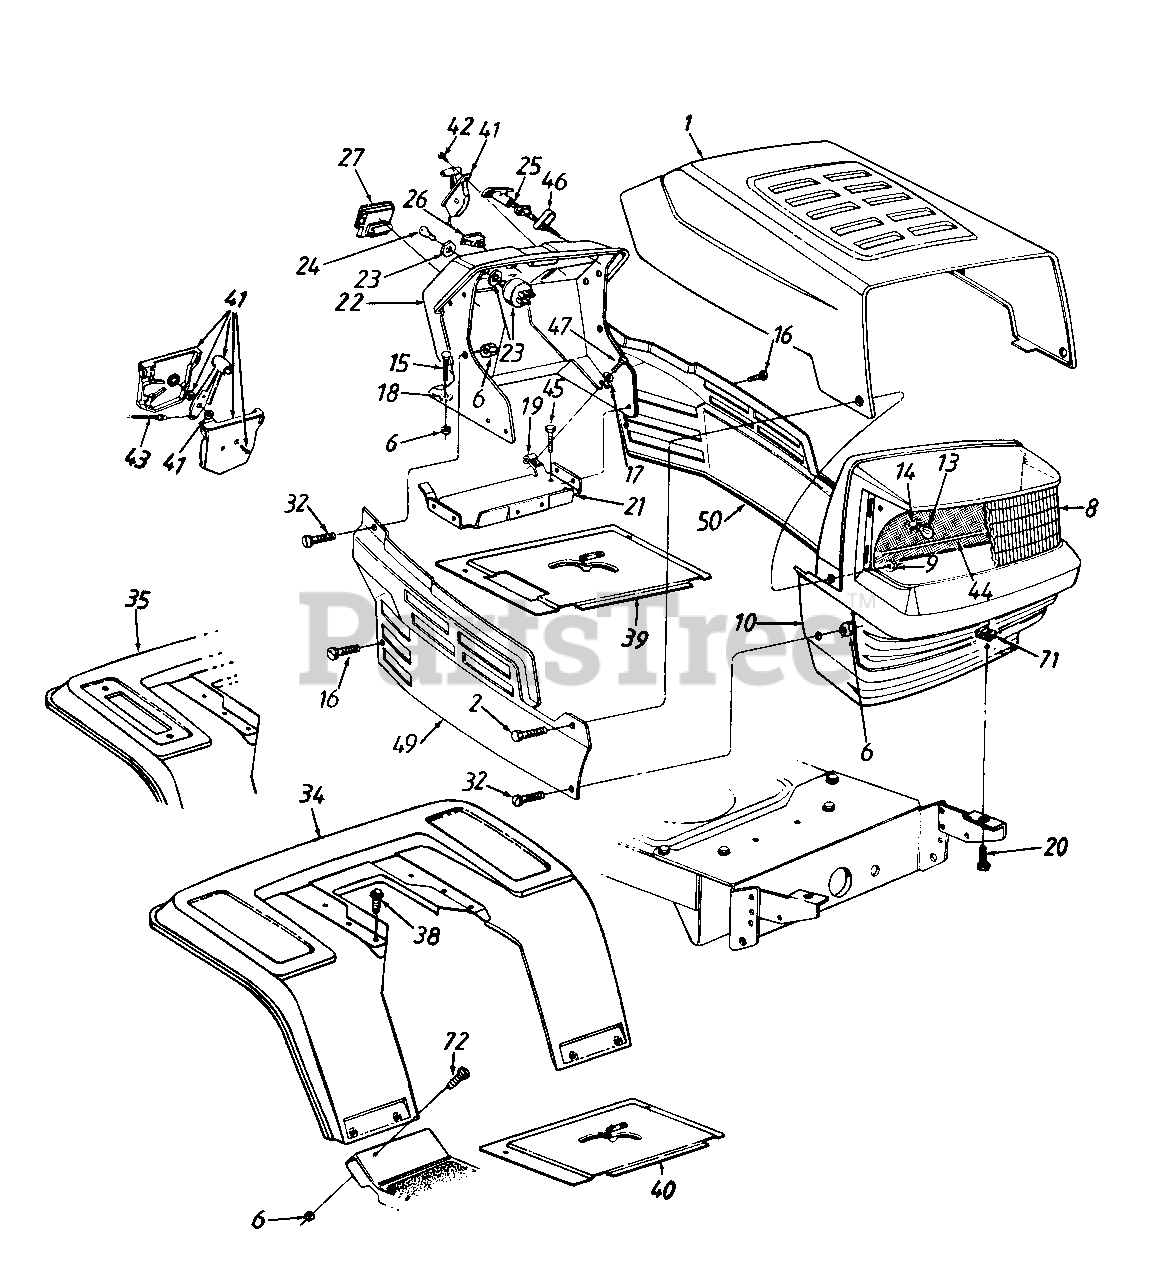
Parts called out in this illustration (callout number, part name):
6	Hex Sems Nut 1/4-20 Thd.
8	Headlight Lens
9	Flange L-Nut 1/4-20 Thd.
10	Grille
13	Lamp
14	Socket
15	Carriage Bolt 1/4-20 x .75" Lg.
16	Hex Wash. Hd. TT-Tap Scr. 1/4-20 x .5" Lg.
17	Fl-Wash. .281" I.D. x .73" O.D.
18	Bolt Retainer 1/4" I.D.
19	Speed Nut 1/4-20 Thd.
20	Hex Bolt 5/16-18 x .75" Lg.
23	Ignition Switch
24	Ignition Key
25	Choke Control
26	Light Switch
27	Ammeter
32	Pan Hd. Scr. 1/4-20 x .75" Lg
41	Throttle Box Ass'y
42	Truss Mach. AB-Tap Scr #10 x 5" Lg.
43	Throttle Control Wire
44	Grille Reflector Label
45	Hex Wash Hd. B-Tap Scr 5/16-18 x .5" Lg
46	Choke Retainer
47	Hex TT-Tap Scr. 1/4-20 x 75" Lg.
72	Truss Mach. Scr. 1/4-20 x .5" Lg.
